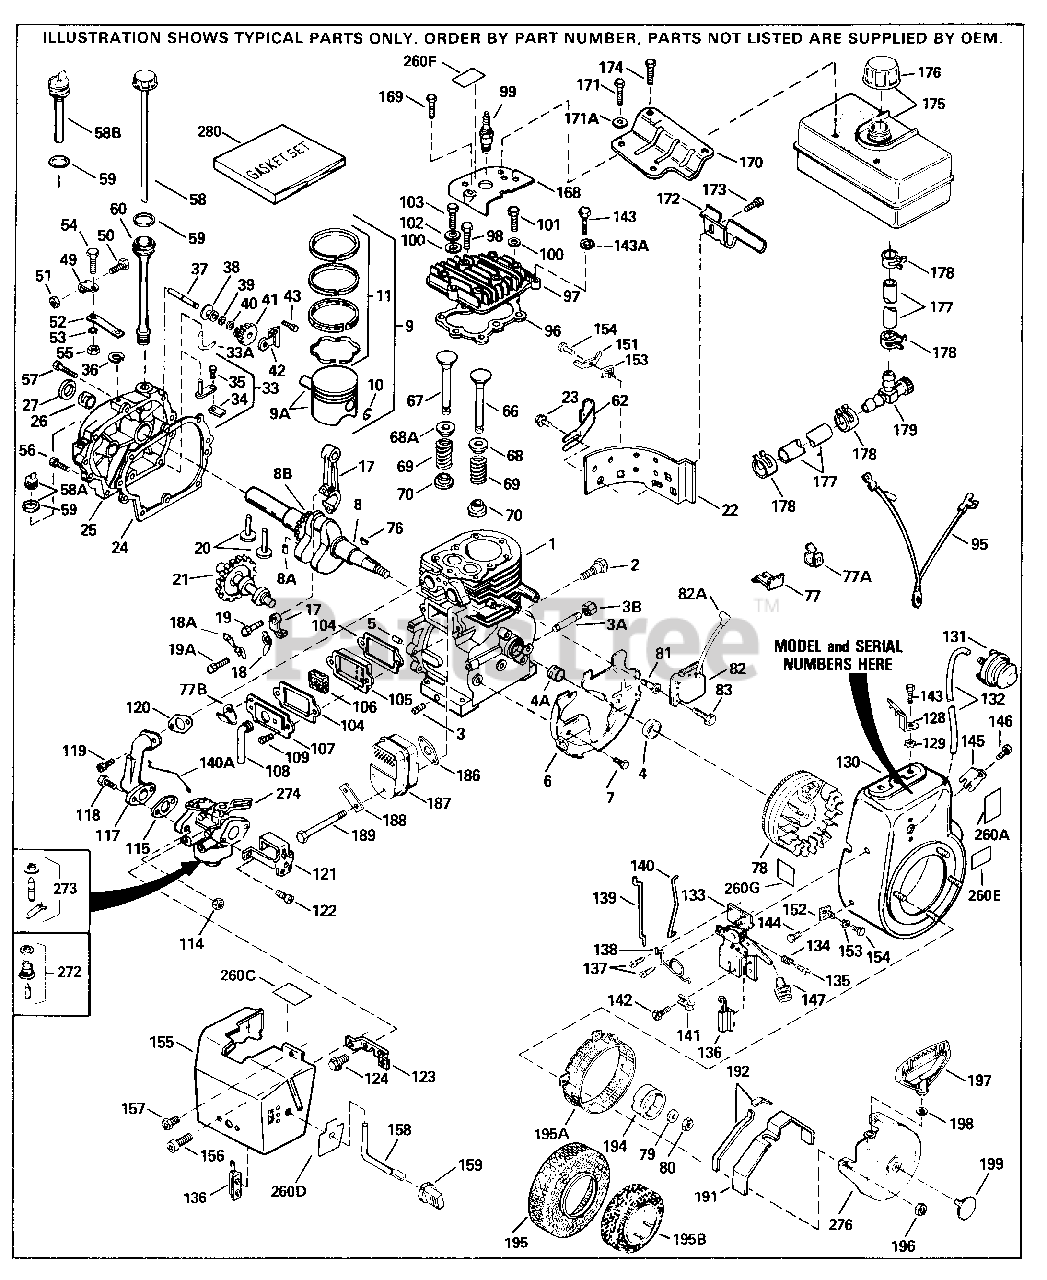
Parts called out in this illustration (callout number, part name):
1	"Cylinder (Incl. 3, 4 & 5) 2-15/16" Bo re
3	Oil Drain Plug (Sq. hd., 1/4-18)
4	Seal, Oil
5	Dowel Pin
6	Blower Housing Baffle (No knock-out f or electric start) (Use as required)
6	Blower Housing Baffle (With knock-out for electricstart) (Use as required)
7	Screw, 1/4-20 x 5/8"
8	Crankshaft
8A	Pin, Crankshaft gear od.)
8B	Crankshaft Gear Used on early product ion
9	Piston, Pin & Ring Set (Std.) 2-15/1 6"
9	Piston, Pin & Ring Set (.010" OS)
9	Piston, Pin & Ring Set (.020" OS)
9A	Piston & Pin Ass'y. (Std.)(Incl. 10) 2-15/16"
9A	Piston & Pin Ass'y. (.010" OS) Incl. 10
9A	Piston & Pin Ass'y. (.020" OS) Incl. 10
10	Piston Pin Retaining Ring
11	Ring Set (Std.) (2-15/16" Bore)
11	Ring Set (.010" OS)
11	Ring Set (.020" OS)
17	Rod Assy., Connecting (Incl. 18 & 19)
18	Dipper, Oil
18A	Plate, Lock & Oil dipper This plate m ay be replaced by No. 34242 oil dippe r but No. 650662C screw must be used.
19	Bolt, Connecting rod (2 pcs.)
20	Lifter, Valve
21	Camshaft (MCR)
22	Extension, Blower housing
23	Screw, 10-24 x 1/2"
24	* Gasket, Cylinder cover
25	Cover, Cylinder Incl. 26, 27, 37, 58 A & 59
26	Bushing, Crankshaft
27	Seal, Oil
33	Rod Assy., Governor (Incl. 34 & 35)
33A	Rod, Governor This one piece governor rod is no longer used. It is replace d by No. 30699C assembly, Ref. No. 5A .
34	Yoke, Governor
35	Screw, 6-40 x 5/16"
36	Retaining Ring
37	Shaft, Mechanical governor
38	Spool, Governor
39	Washer, Flat
40	Retaining Ring
41	Gear Assy., Governor (Incl. 39)
42	Bracket, Governor gear
43	Screw, 10-24 x 1/2"
49	Governor Lever Clamp
50	Screw, 10-32 x 3/4"
51	Lock Nut, 10-32
52	Lever Assy., Governor
53	Lock Washer #8
54	Screw, 8-32 x 5/16"
55	Lock Nut, 8-32
56	Screw, 1/4-20 x 1-11/16"
57	Screw, 1/4-20 x 1-3/16"
58	Dipstick (Incl. 59)
58A	Oil Fill Plug (Incl. 312) also availa ble in Packaged Part #740079
59	* Gasket, Oil fill
60	Oil Fill Tube
66	Exhaust Valve (Std.)(Incl. 151)
66	Exhaust Valve (1/32" OS) (Incl. 151)
67	Intake Valve (Std.) (Incl. 70)
67	Intake Valve (1/32" OS) (Incl. 70)
68	Valve Spring Cap
68A	Valve Spring Cap
69	Valve Spring
70	Cap, Lower valve spring
76	Key, Flywheel
79	Washer, Belleville
80	Nut, Hex
82A	Spark Plug Cover
82A	Cover, Spark plug (Use as required)
83	Screw, 1/4-20 x 5/8"
95	Ground Wire (Incl. 164)
96	* Gasket, Cylinder head
97	Head, Cylinder
98	Screw, 5/16-18 x 1-1/2" Use as requir ed, but do notuse No. 650691 washer.
98	Screw, 5/16-18 x 1-3/4" Use as requir ed
98	Screw, 5/16-18 x 1-5/8" (Use as requi red) (Can use No. 6021A but discard N o. 650691 washer.)
99	Resistor Spark Plug (RJ17LM)
100	Washer (Use as req.) Do not use w/60 21A
101	Screw, 5/16-18 x 1-3/4" Use as requir ed
104	* Gasket, Breather
105	Breather Body
106	Breather Element
107	Valve Cover
108	Breather Tube
109	Screw, 10-24 x 1/2"
114	Nut & Lock Washer 1/4-28
115	* Gasket, Carburetor
117	Pipe, Intake
118	Screw, 1/4-28 x 1"
119	Screw, Torx T-30, 5/16-18 x 1-1/8"
120	* Gasket, Intake
128	Clip, Spark plug shorting
129	Washer, Lock
130	Blower Housing (For electric starter)
136	Terminal Assy. (Use as required)
140	Link, Governor lever-to-throttle
143	Screw, 5/16-18 x 3/4"
144	Screw, T-40, 5/16-24 x 21/32"
145	Cover, Starter bubble
146	Screw, 8-32 x 3/8"
151	Terminal, Ground
153	Breather Tube Grommet
154	Screw, 8-32 x 3/8"
158	Rod, Choke
168	Cover, Cylinder head
169	Screw, 5/16-18 x 5/8" Use as require d
169	Screw, 1/4-20 x 1/2" Use as required
169	Screw, 1/4-20 x 5/8" Use as required
170	Plate, Upper fuel tank mounting
171	Screw, 5/16-18 x 5/8" Use as require d
172	Bracket Assy., Lower fuel tank mtg.
173	Screw, 1/4-20 x 5/8"
174	Screw, 1/4-15 x 7/8"
175	Fuel Tank (Incl. 176 & 178) NOTE: Th ese tanks were built with different s ize fuel inlet openings. Tanks with t he 1-3/16" I.D. opening use fuel cap 33032 or 34210. Tanks with the 1-1/2 " I.D. opening use fuel cap 35355.
176	Fuel Cap (Red 1-1/2" ID) (also availa ble in Packaged Part #740005B) (Red Plastic) (Spurt Resistant, Low Profil e) (Use as required)
176	Fuel Cap (Ref Plastic) (Spurt Resista nt, High Profile) (Use as required)
176	Fuel Cap (Red) ed)
176	Fuel Cap (White Plastic) (Std) Use as req.
177	Fuel Line (8.62") 21 cm)
177	Fuel Line (Use as required) (16.0") 41 cm
178	Fuel Line Clamp
186	* Gasket, Exhaust (Use as required)
195B	Hub & Screen Assy., Starter
196	Nut & Lock Washer 1/4-28
273	Inlet Needle, Seat & Clip Assy.
274	Carburetor (Incl. 115) (Refer to Divi sion 5, Section A, page 150 for break down)
276	Rewind Starter Refer to Division 5, S ection C, page 30 for breakdown
280	* Gasket Set (Incl. items marked *)
